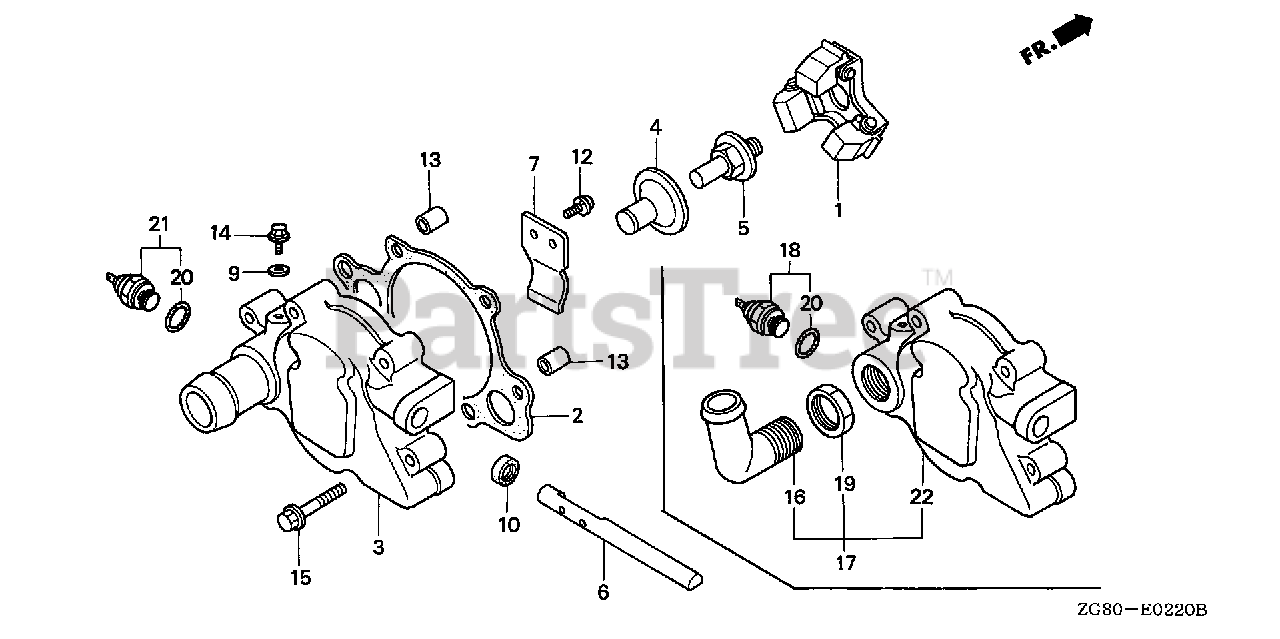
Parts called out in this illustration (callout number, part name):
1	WEIGHT, GOVERNOR
2	GASKET, GOVERNOR COVER
3	COVER, GOVERNOR
4	SLIDER, GOVERNOR
5	SHAFT, GOVERNOR
6	SHAFT, GOVERNOR
7	FORK, GOVERNOR
9	WASHER, SEALING (6MM)
10	OIL SEAL (10X16X4.5)
12	SCREW-WASHER (5X12)
13	PIN, DOWEL (8X14)
14	BOLT, FLANGE (6X14)
15	BOLT, FLANGE (6X35)
